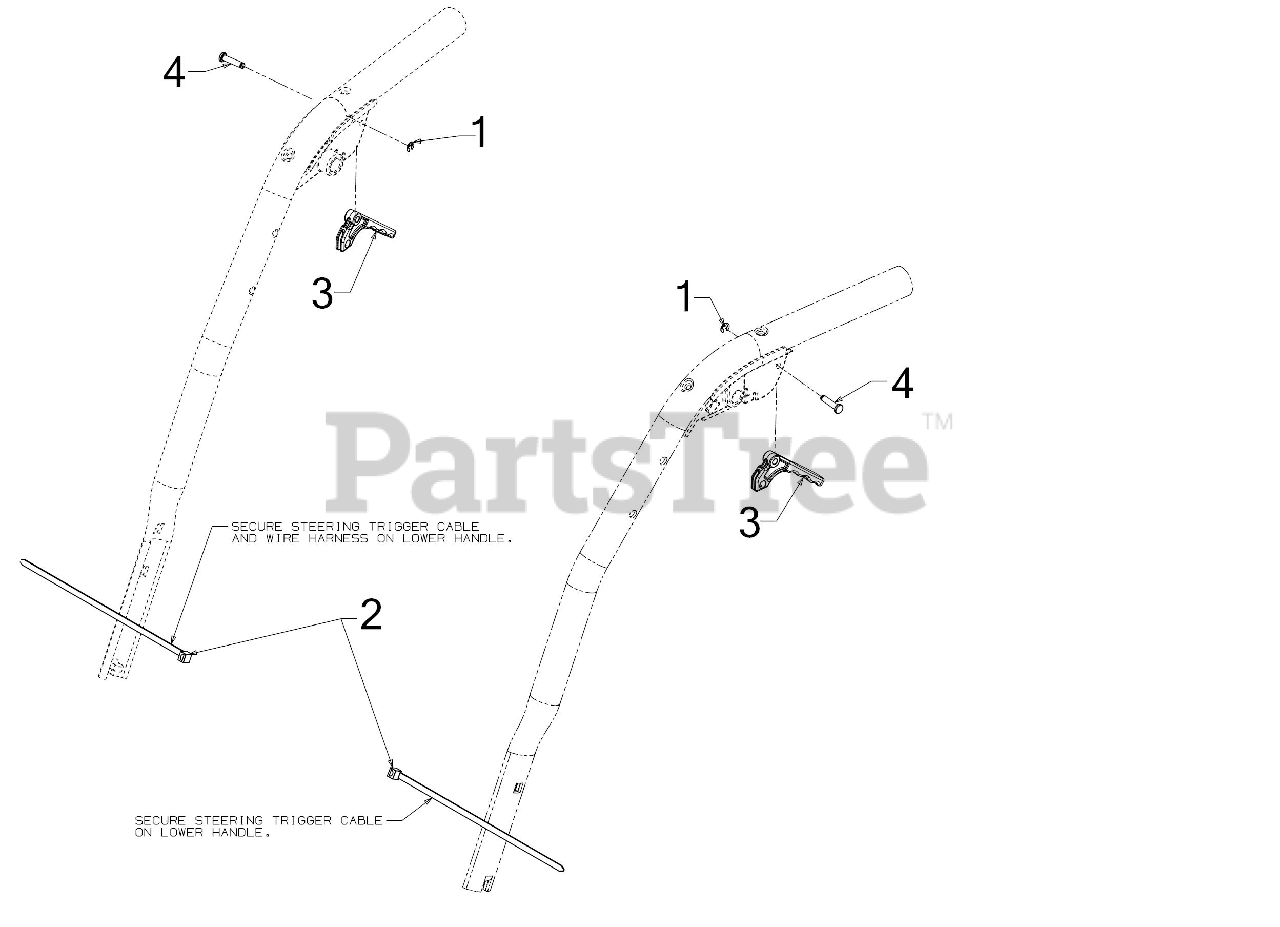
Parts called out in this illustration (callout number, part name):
1	E-RING
2	7" CABLE TIE
3	STEERING CONTROL TRIGGER
4	STEERING TRIGGER PIN 3/16
